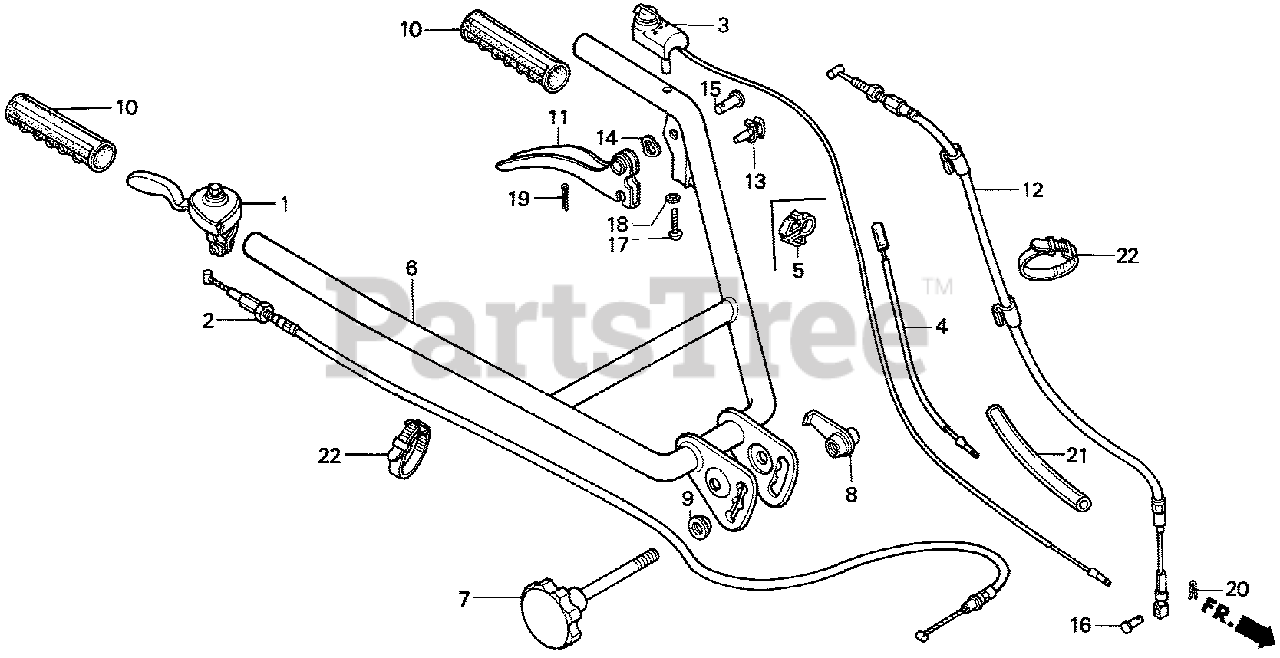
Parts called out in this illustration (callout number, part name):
1	LEVER ASSY., THROTTLE
2	CABLE, THROTTLE
3	SWITCH ASSY., STOP (NOT AVAILABLE)
7	ADJUSTER, HANDLE
8	NUT, HANDLE LOCK
9	NUT, SPECIAL (10MM)
10	GRIP, HANDLE
11	LEVER, CLUTCH (NOT AVAILABLE)
12	CABLE, CLUTCH
13	CLIP, DOOR CABLE (NOT AVAILABLE)
14	WASHER, WAVE (10MM)
15	PIN (8X18)
16	PIN (4X15.5) (NOT AVAILABLE)
17	SCREW, PAN (3X12)
18	WASHER, SPRING (3MM)
19	PIN, COTTER (2.0X15)
20	PIN, LOCK (4MM)
21	BULK HOSE, VINYL (12X16X3000) (12X16X130)
22	BAND B1, CABLE
